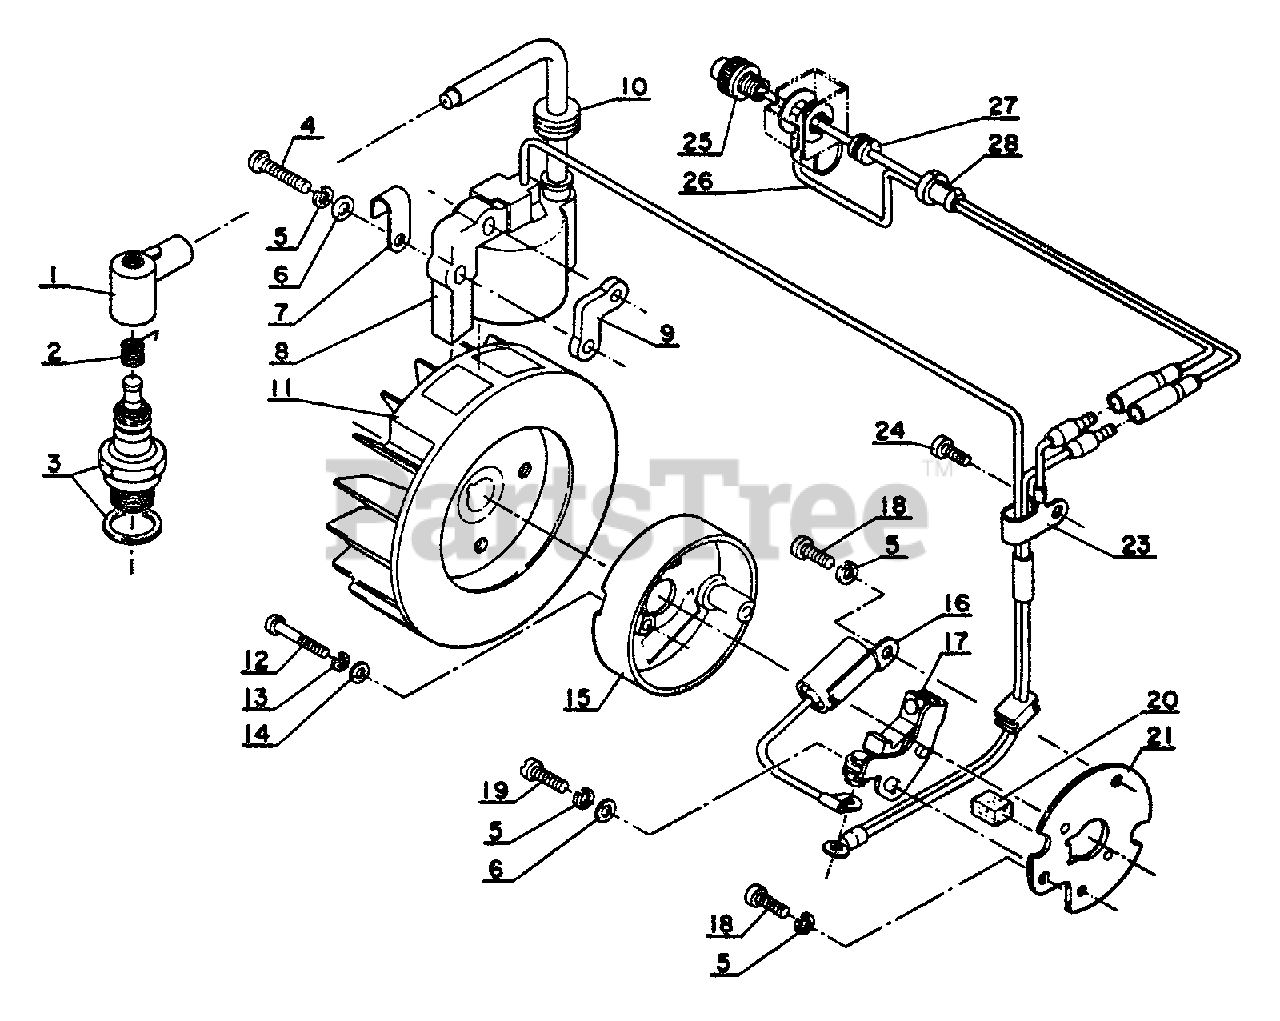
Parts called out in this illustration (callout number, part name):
1	CAP, SPARK PLUG
2	TERMINAL, SPARK PLUG CAP
3	SPARK PLUG -- BM-6A
5	LOCKWASHER - 4
6	WASHER - 4
7	Clip (B)
8	COIL, IGNITION
9	SPACER
11	FLYWHEEL
12	SCREW - 3X20
13	LOCKWASHER - 3
14	WASHER - 3
15	COVER, BREAKER
16	CONDENSER
17	CONTACT POINT SET
18	SCREW - 4X10
19	SCREW - 4X12
20	PAD
21	PLATE, STATOR
23	CLIP A
24	SCREW - 4X8
25	Stopper button
26	LEAD - GROUND
27	GROMMET
28	BUSHING
